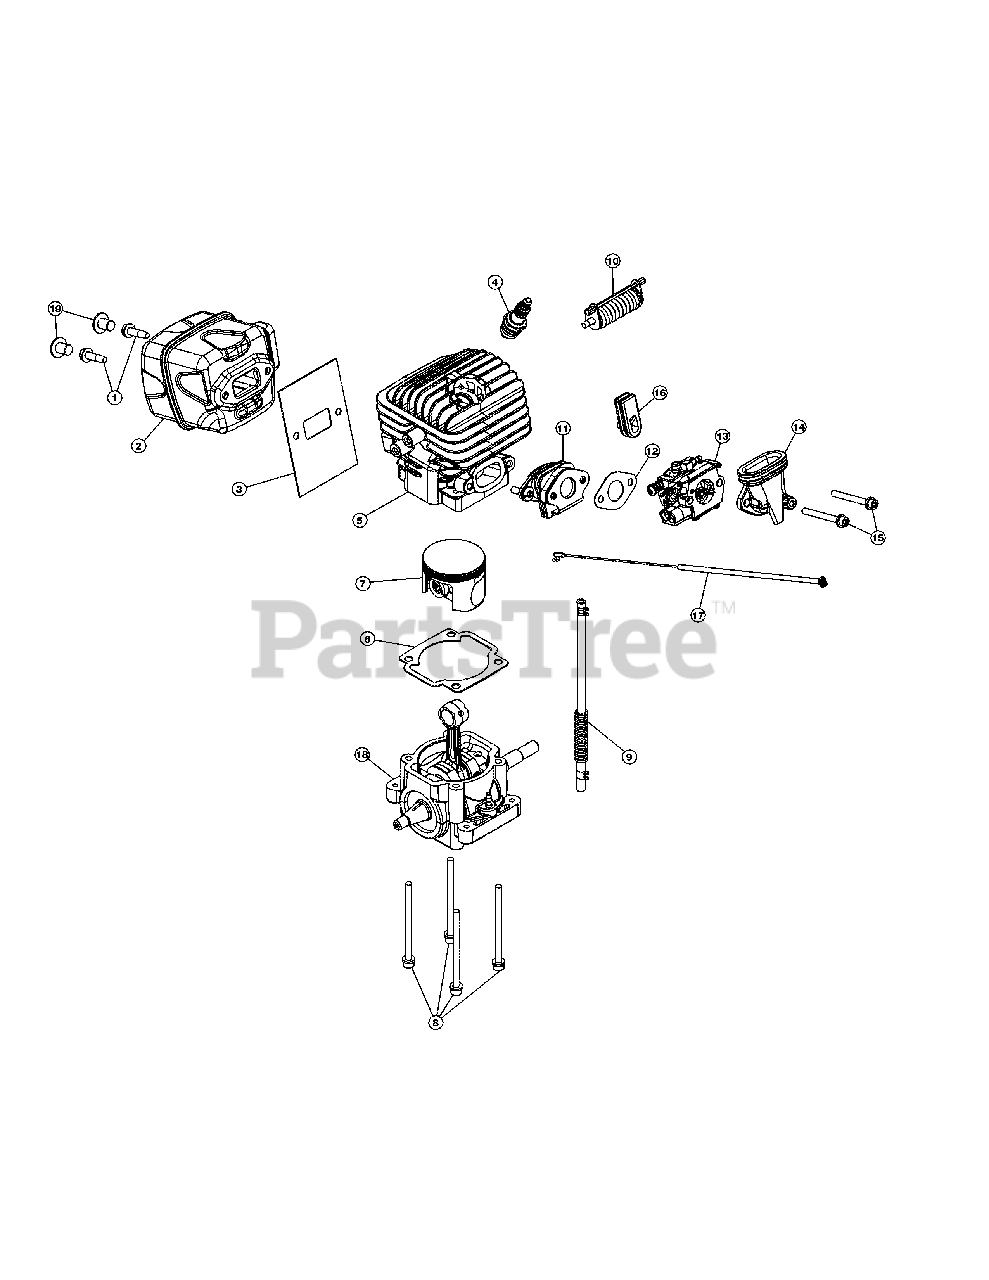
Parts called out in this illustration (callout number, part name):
1	Muffler Screw
2	Muffler Assembly (Incl. 1, 3 & 19)
3	Muffler Gasket
4	Spark Plug
5	Cylinder Assembly (Incl. 6, 8 & 10)
6	Cylinder Gasket
7	Piston Assembly
8	Cylinder Hardware
9	Breather Hose w/clamp
10	Isolator Assembly
11	Insulator Assembly
12	Carburetor Gasket
13	Carburetor
14	Boot & Bracket Assembly (Incl. 16 & 17)
15	Carburetor Hardware
16	Grommet
17	Throttle Cable
18	Shortblock Assembly (Incl. 4-10)
19	Muffler Plug
